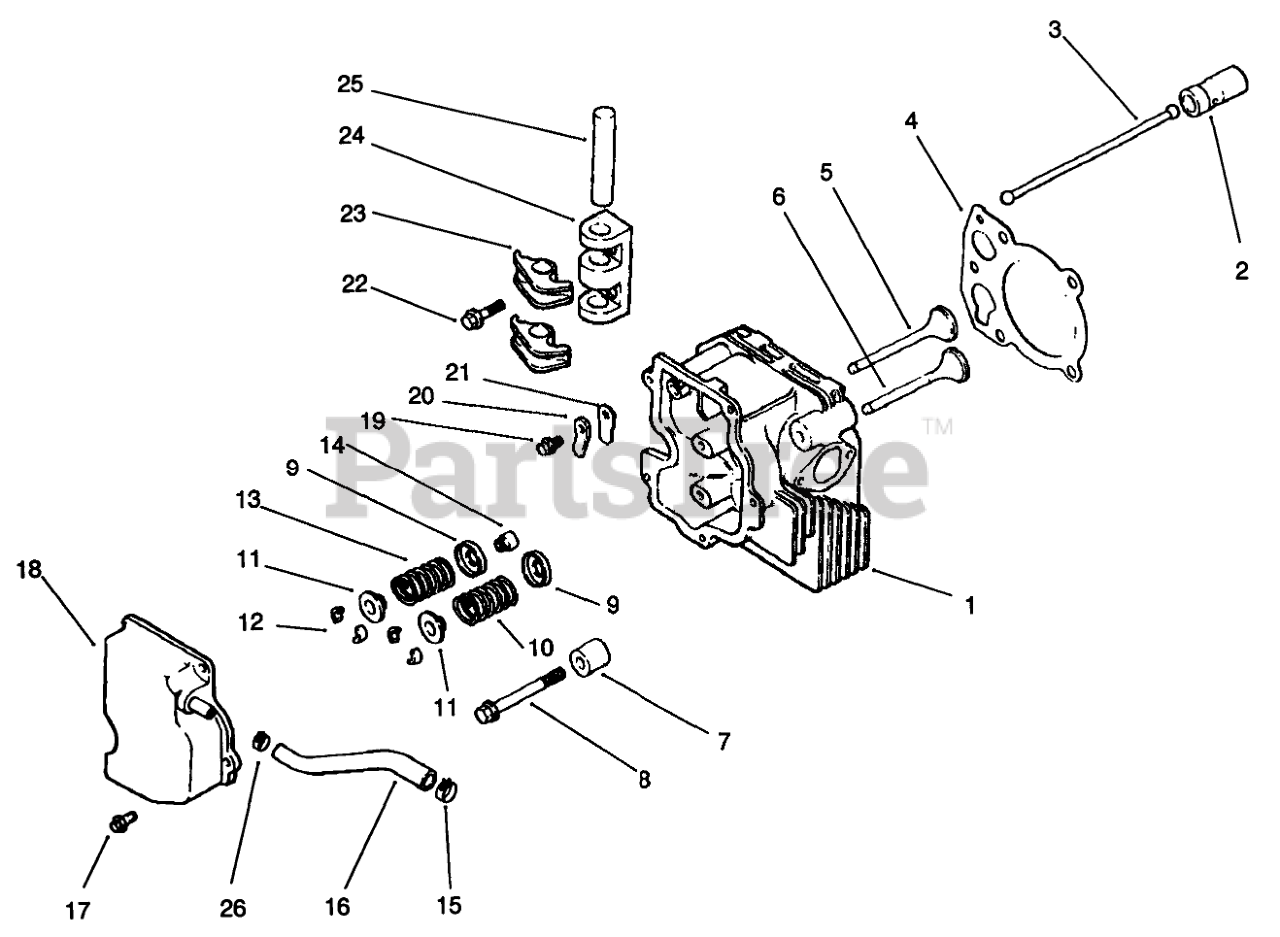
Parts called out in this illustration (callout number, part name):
1	Cylinder Head
2	Lifter-Valve
3	Rod-Push
4	Gasket-Cylinder Head
5	Valve-Intake STD
5	Valve-Intake .25
6	Valve-Exhaust STD
6	Valve-Exhaust .25
7	Spacer-Head Bolt
8	Screw-Cylinder Head
9	Retainer-Spring
10	Spring-Valve Intake
11	Cap-Valve Spring
12	Kit-Retainer
13	Spring-Valve, Intake
14	Seal
15	Clamp
16	Hose-Breather
17	Screw
18	Cover-Valve
20	Retainer-Reed
22	Screw
23	Arm-Rocker
24	Bridge-Rocker Arm
25	Shaft-Rocker Arm
26	Clamp-Hose
